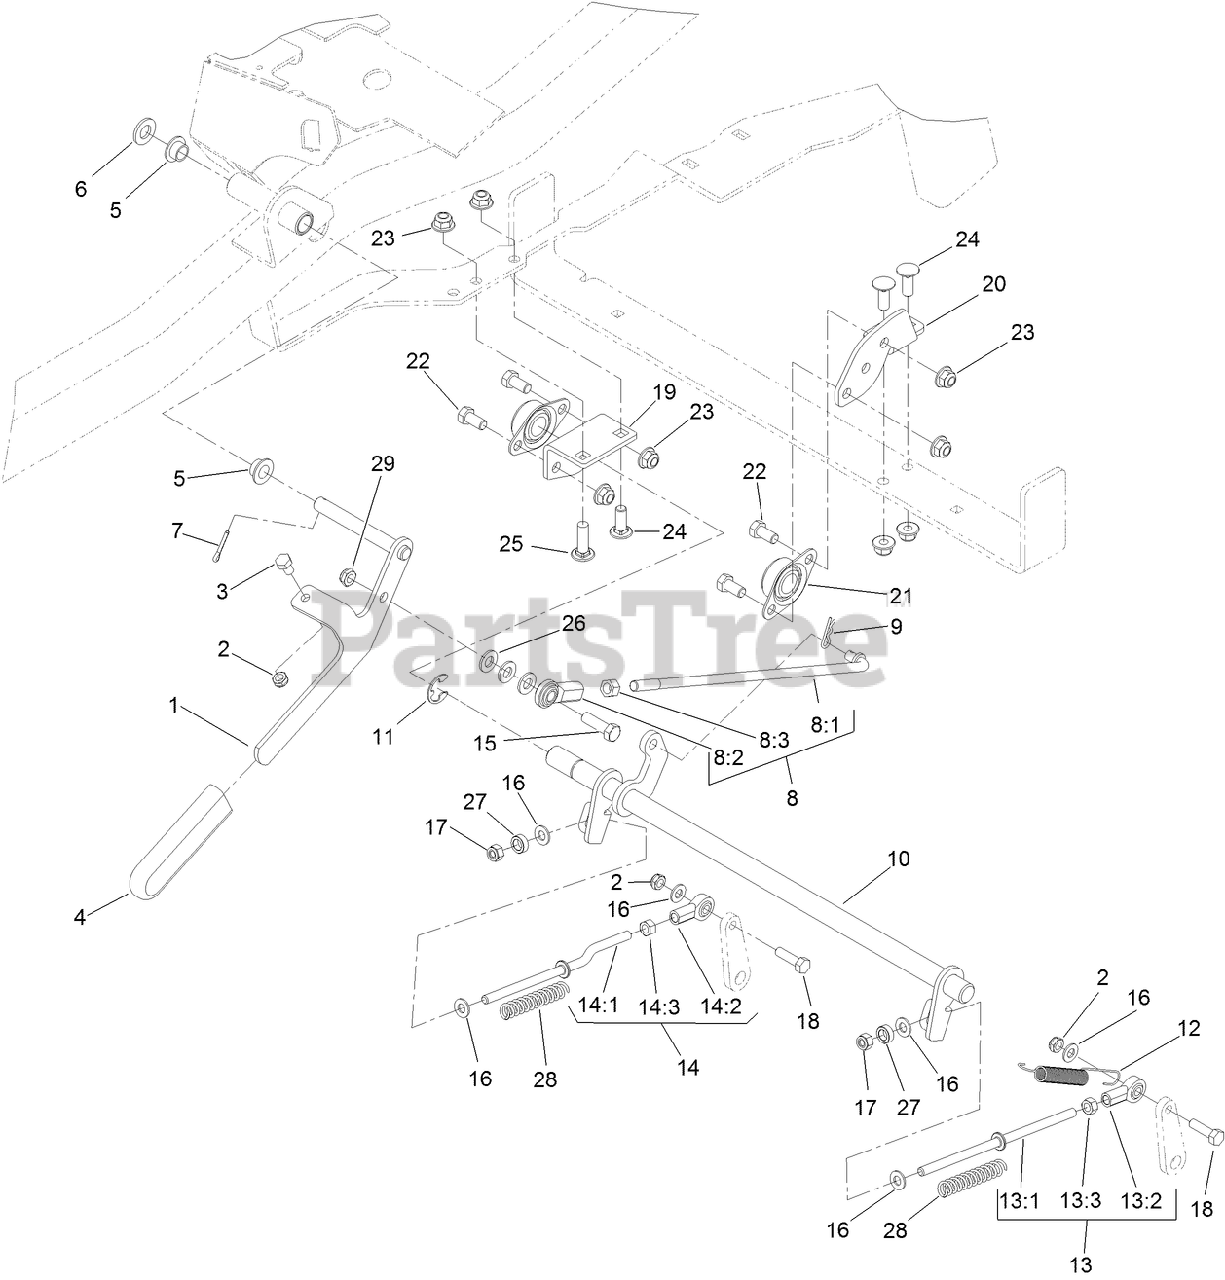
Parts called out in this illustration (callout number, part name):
1	HANDLE-BRAKE
2	NUT-LOCK, NI
3	SCREW-HH
4	GRIP-LEVER
5	BEARING-CONTROL
6	WASHER-FLAT
7	PIN-COTTER
8	BRAKE LINK ASM
8:1	ROD-LINK, BRAKE
8:2	JOINT-BALL, END
8:3	NUT-HEX
9	PIN-COTTER
10	SHAFT-BRAKE
11	E-RING
12	SPRING-EXTENSION
13	LH BRAKE ROD ASM
13:1	ROD-BRAKE
13:2	BALLJOINT-RH
13:3	NUT-HEX
14	RH BRAKE ROD ASM
14:1	ROD-BRAKE
14:2	BALLJOINT-RH
14:3	NUT-HEX
15	SCREW-HH
16	WASHER-PLAIN
17	NUT-LOCK
18	SCREW-HH
19	BRACKET-SHAFT MOUNT, RH
20	BRACKET-SHAFT MOUNT, LH
21	BEARING-FLANGE, SIDE
22	SCREW-HH
23	NUT-HF, NI
24	SCREW-CARR
25	SCREW-CARR
26	WASHER-FLAT
27	SPACER
28	SPRING-RETURN, NEUTRAL
29	NUT-LOCK, NI
